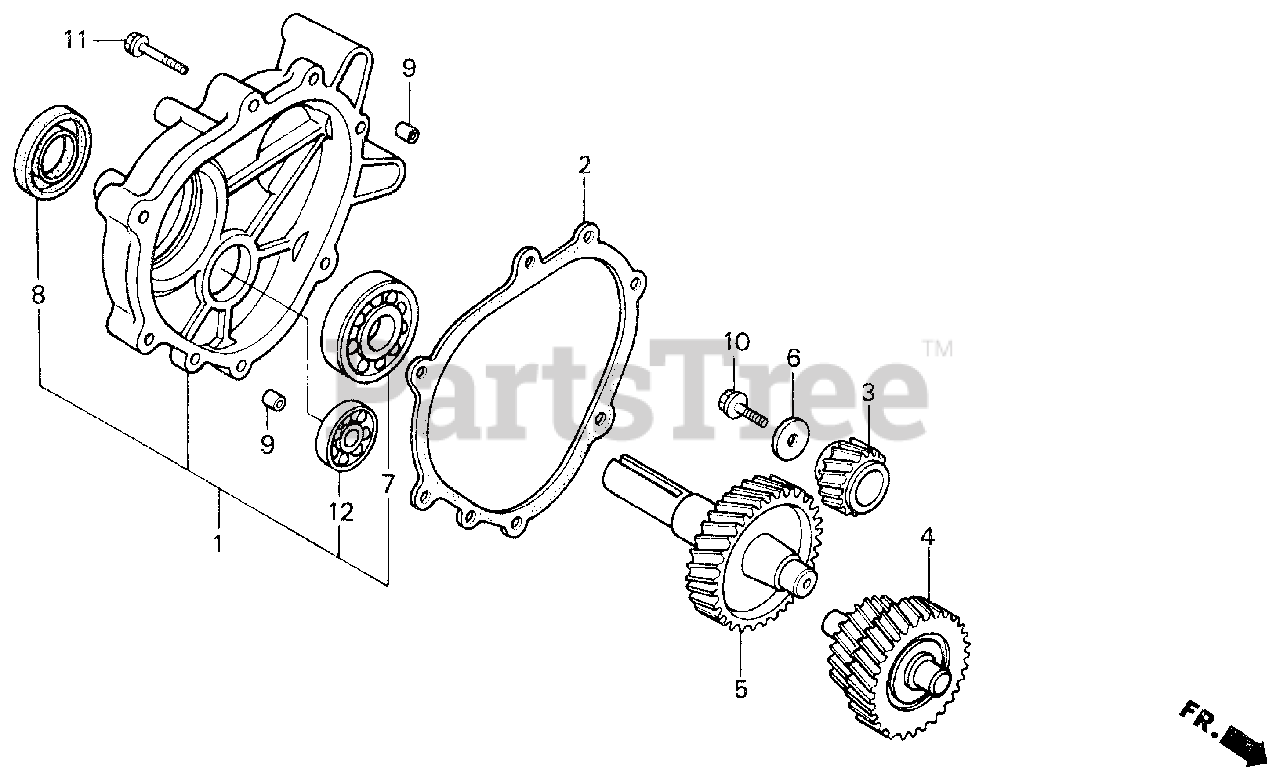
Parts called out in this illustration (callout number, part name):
1	COVER ASSY., GEAR CASE
2	GASKET, CHAIN CASE COVER
3	GEAR, PRIMARY DRIVE
4	COUNTERSHAFT
5	SHAFT, P.T.O. (L-TYPE)
6	WASHER (8MM)
7	BEARING, RADIAL BALL (6206)
8	OIL SEAL (30X46X8)
9	PIN A, DOWEL (8X14)
10	BOLT, HEX. (8X25)
11	BOLT, FLANGE (8X40)
